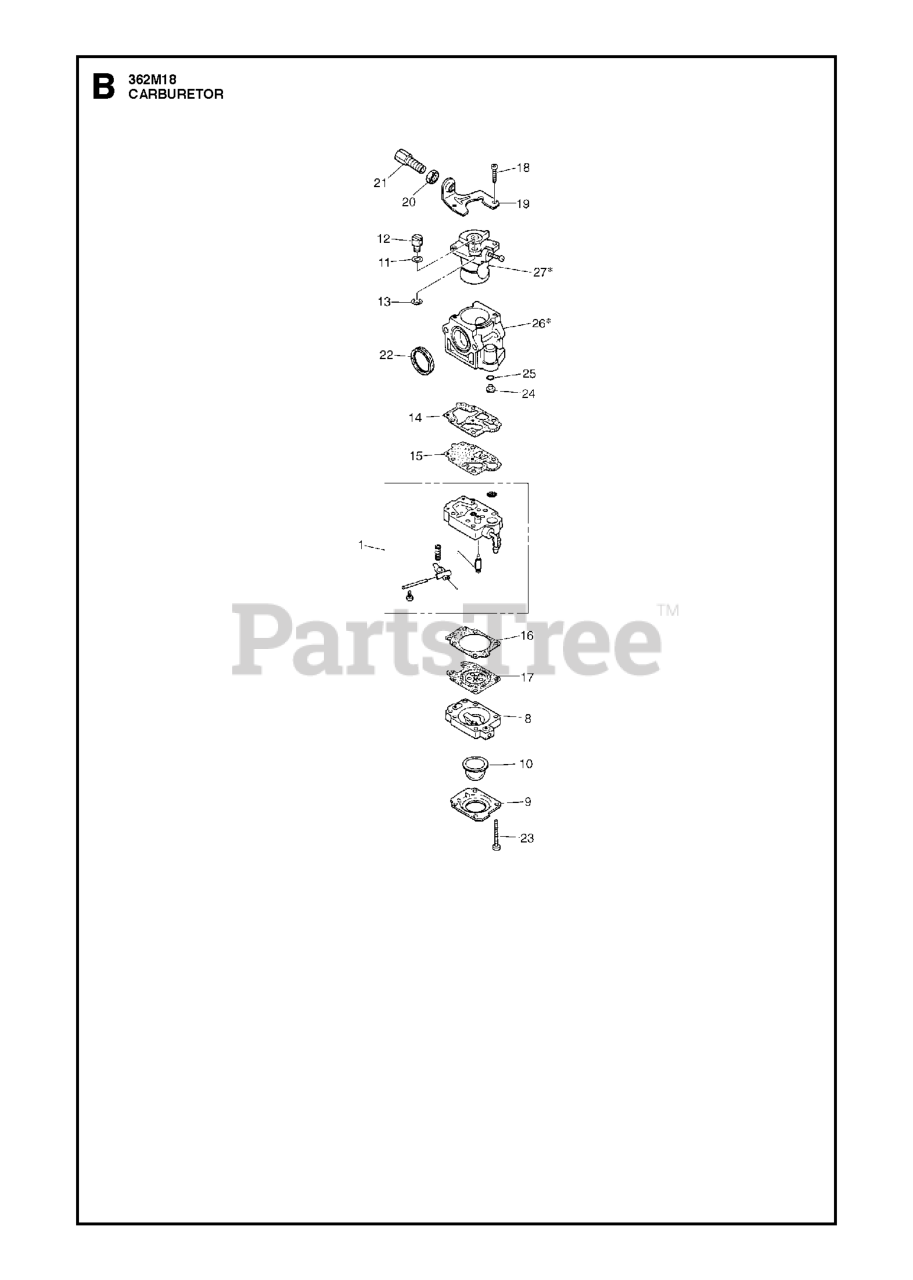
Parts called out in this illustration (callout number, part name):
1	CARBURETOR BODY
14	GASKET
20	NUT
21	ADJUSTER
22	RING PACKING
